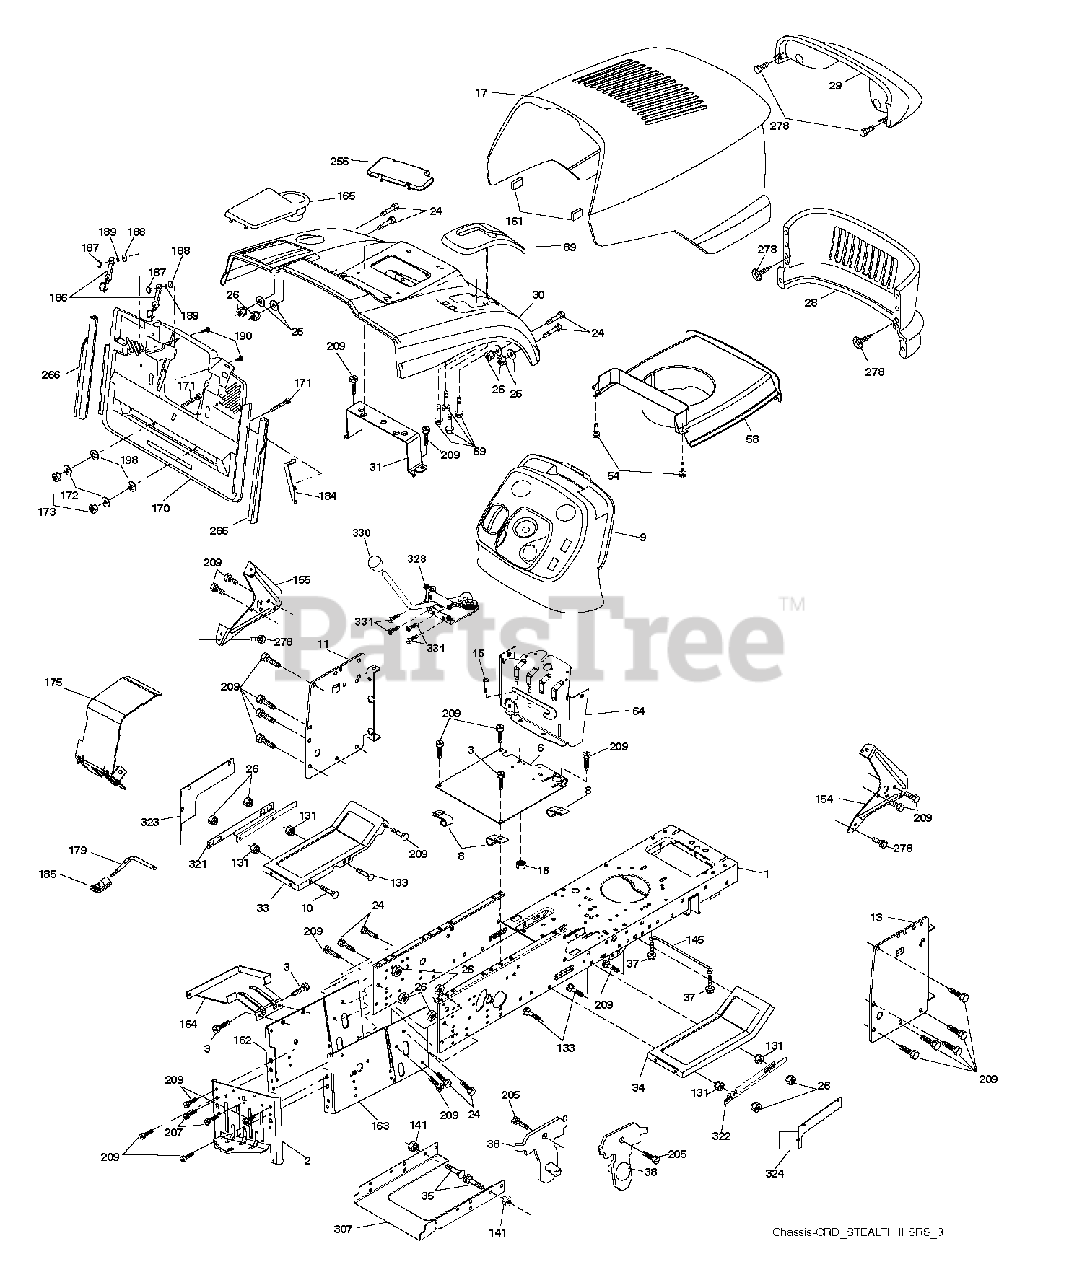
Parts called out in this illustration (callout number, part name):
1	CHASSIS
3	SCREW 3/8-16X3/4
8	CLIP,INSULATOR
10	BOLT.3/8-14X1.25
13	PANEL DASH RH
16	NUT
25	WASHER
26	NUT
31	BRACKET SUPPORT FENDER
54	SCREW.WSHD.HEX10-32X5/8
58	DUCT HOOD
69	SCREW.HI-LO.CONSOLE
131	NUT.HEX.3/8-16UNC
141	NUT LOCK FLG 3/8-16 UNC
145	ROD.PIVOT.HOOD
161	EXTRUSION BUMPER
164	SUPPORT
171	BOLT
172	WASHER
186	LATCH ASSY
187	WELDNUT
189	LOCKWASHER
207	SCREW, 5/16-18 X 1/2
209	SCREW, 3/8-16X3/4
278	SCREW.#10 X 0.750.BOS THREAD
331	SCREW.#10-24X5/8.RN.QU
